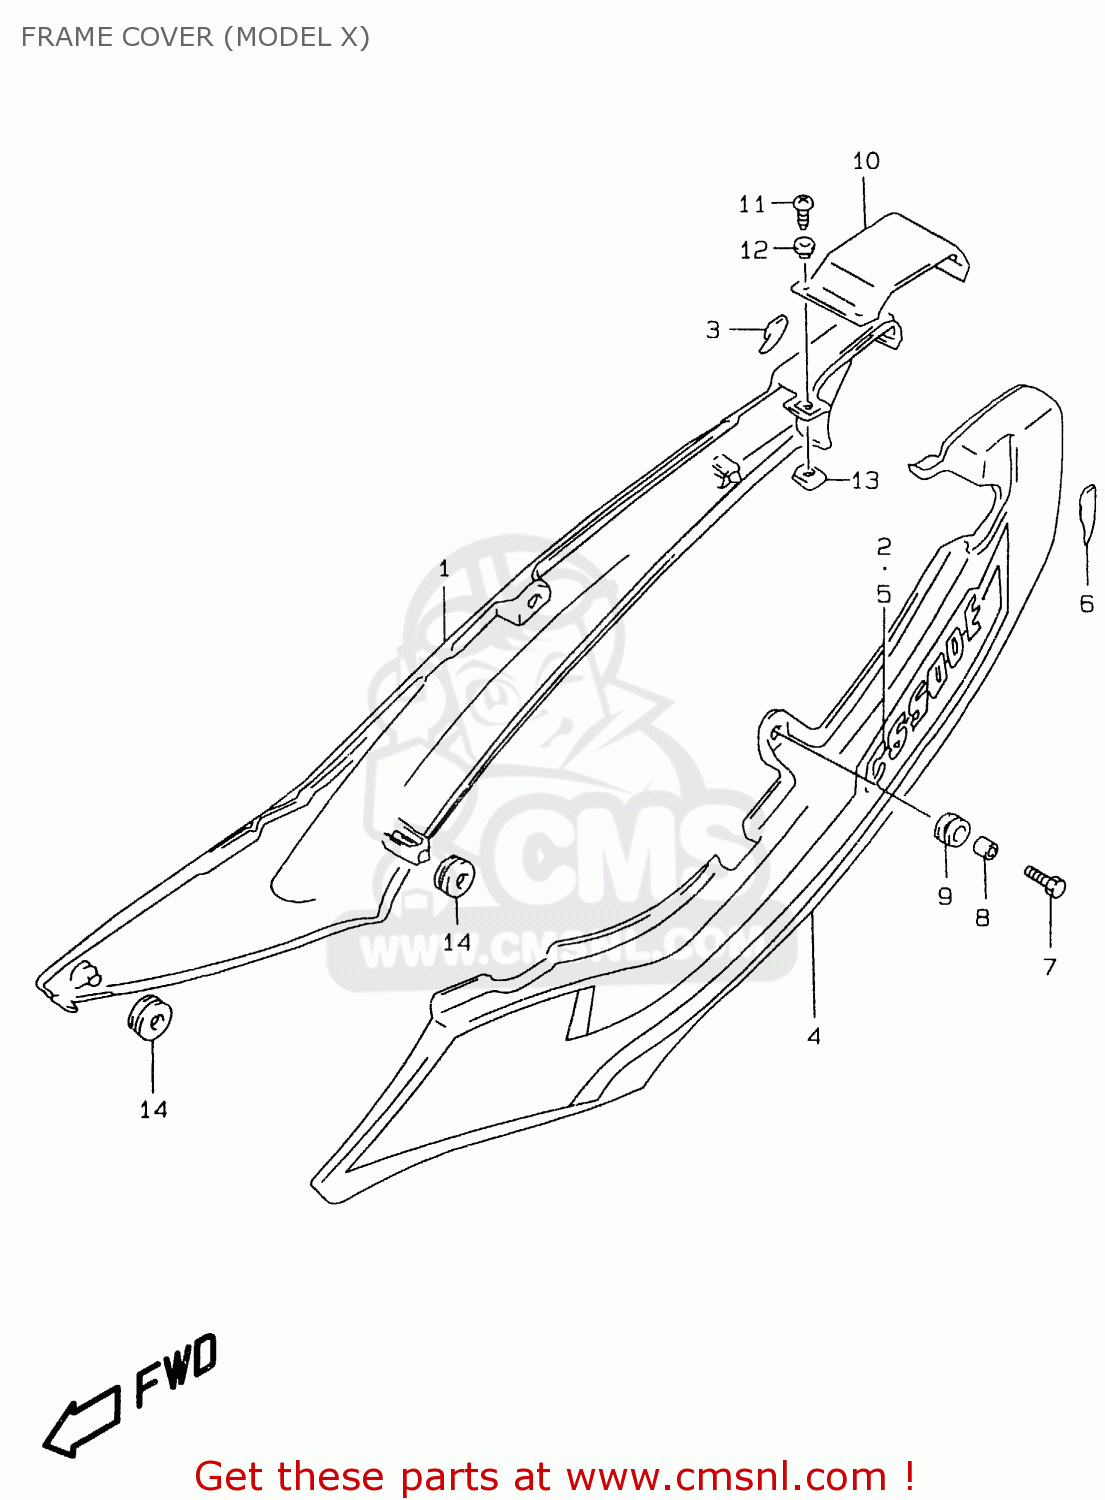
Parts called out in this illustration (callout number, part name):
1	COVER,FRAME,R(BLACK)
2	TAPE,FRAME COVER,R
3	PROTECTOR,FRAME COVER,R
4	COVER,FRAME,L(BLACK)
5	TAPE,FRAME COVER,L
6	PROTECTOR,FRAME COVER,L
7	BOLT(6X20)
8	SPACER(6.5X9X9)
9	CUSHION
10	COVER,FRAME CTR
11	SCREW L:12
12	WASHER(5.2X14X1.5)
13	NUT
14	CUSHION
